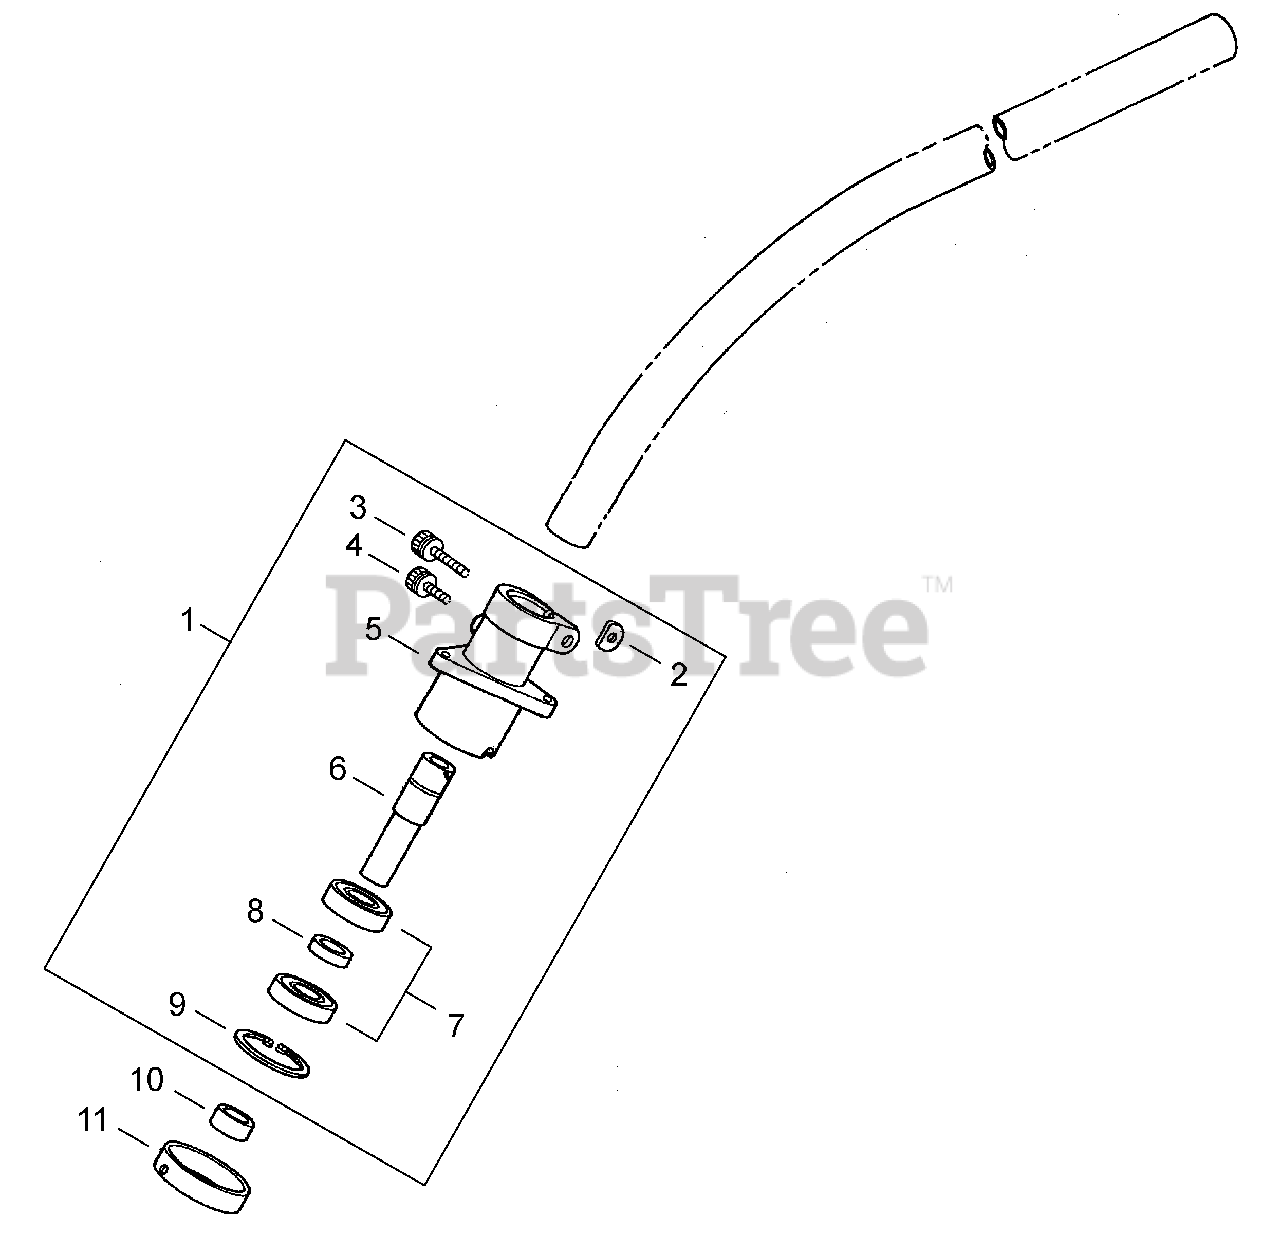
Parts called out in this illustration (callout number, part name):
1	GEAR CASE ASSY
2	D-WASHER
3	BOLT M5×25
4	BOLT
5	HOUSING, GEAR CASE
6	SHAFT
7	BEARING, BALL 6001 DDU
8	COLLAR (A)
9	RING, SNAP Ø28
10	COLLAR (B)
11	HOLDER
